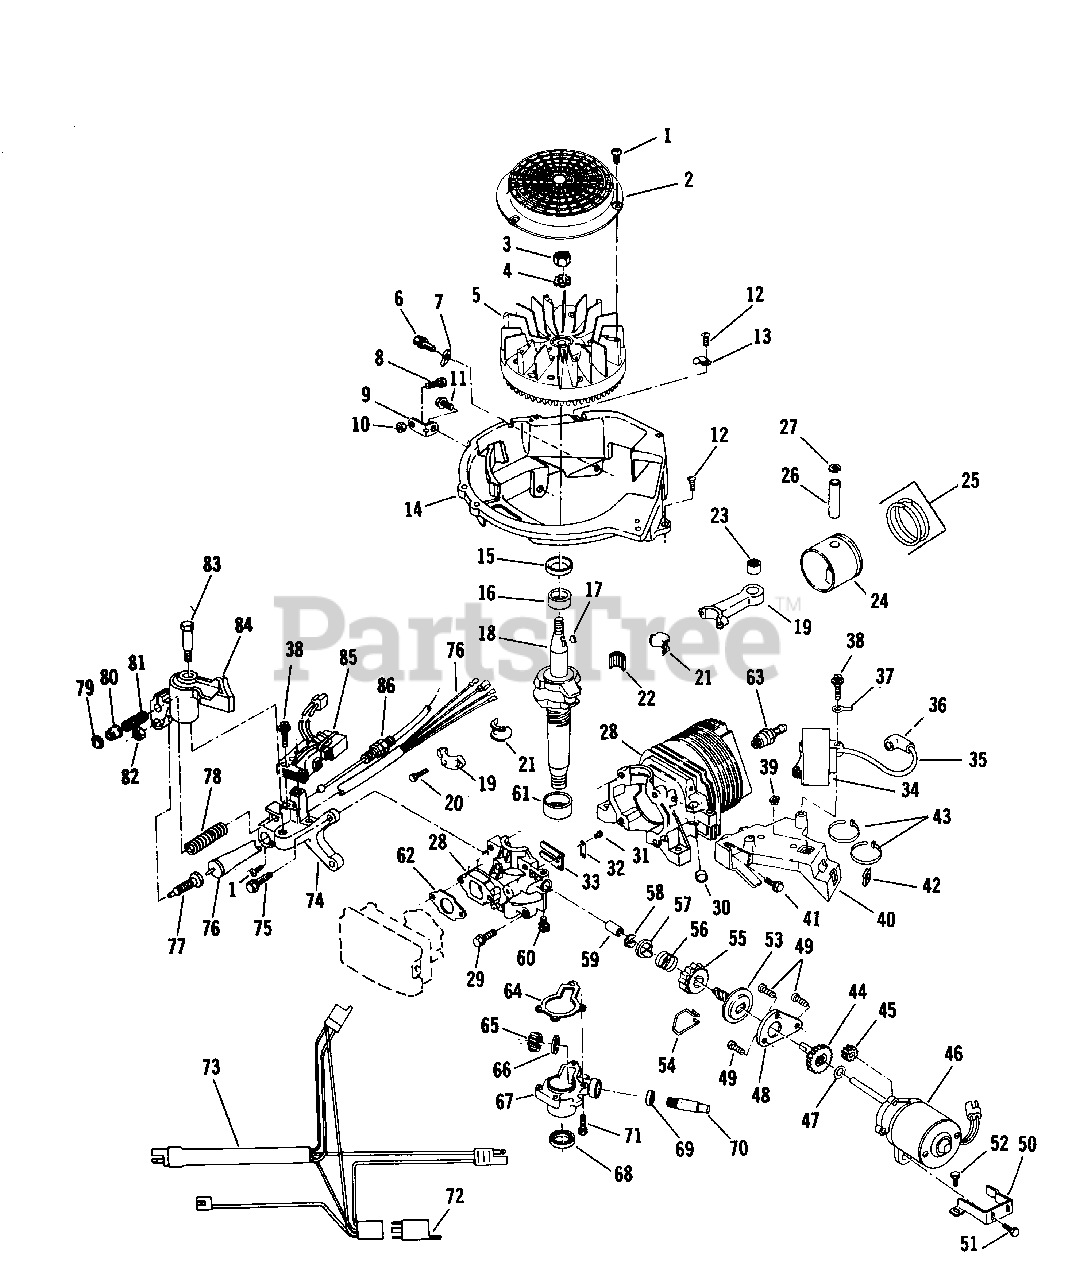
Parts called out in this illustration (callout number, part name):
1	Screw-Flywheel Screen and Switch
2	Flywheel Screen
3	Nut-Flywheel
4	Lockwasher
5	Flywheel
6	Screw
7	"J" Clip
8	Bolt-Brace-Alt. Brkt.
9	Brace-Alt. Bracket
10	Locknut-Brace Alt. Brkt.
11	Screw
12	Screw-Shd. Base to C.D. Brkt. and Clamp to Shd. B.
13	Clamp
14	Base-Shroud
15	Oil Seal-Upper
16	Bearing-Upper
17	Key-Flywheel
18	Crankshaft
19	Connecting Rod Assembly
20	.Screw-Cap
21	Liner Split
22	Needle Bearing Set
23	Bearing Assembly
24	Piston and Ring Set
25	.Ring Set
26	.Wrist Pin
27	.Retaining Ring
28	Cylinder and Crankcase Cover Assembly
29	Screw-Cover to Crankcase
30	Plug
31	Screw-Reed to C'case Cover
32	Plate-Reed Hold Down
33	Reed
34	C.D. Ignition Module and Lead Assembly
35	High Tension Lead and Cover Assembly
36	Spring Terminal
37	Terminal-Ground Lead
38	Screw-C.D. Mtg. and Alt. Mtg.
39	Grommet-C.D. Bracket
40	Bracket-Ignition Mtg.
41	Screw
42	Clip-"U"
43	Tie Strap
44	Gear-Driven
45	Pinion-Motor Shaft
46	Motor Housing and Pin Ass'y.
47	Washer
48	Plate-Gear Cover
49	Screw
50	Bracket-Starter Mtg.
51	Screw-Bracket to Motor
52	Screw
53	Pinion, Spring and Clutch Ass'y.
54	Spring-Drag
55	Pinion
56	Spring-Pinion Return
57	Washer-Pinion Stop
58	Retaining Ring
59	Sleeve
60	Set Screw-Starter Assembly
61	Bearing-Lower
62	Gasket-Carb. to Crankcase Cov.
63	Spark Plug
64	Gasket-Gear Box
65	Gear
66	Washer-Thrust
67	Gear Box Assembly
68	Oil Seal Crankshaft
69	Seal-Driveshaft
70	Driveshaft
71	Screw-Gear Box
72	Relay
73	Wire Harness Assembly
74	Bracket-Alt. and Brake Mtg.
75	Screw-Alt. and Brake Mtg. Brkt.
76	Brake Switch Assembly
77	Plunger
78	Spring-Brake
79	Retainer
80	Actuator-Brake Lever
81	Spring-Cable Retainer
82	Nut
83	Bolt-Shoulder
84	Brake Assembly
85	Alternator Assembly
86	Control Cable Assembly
